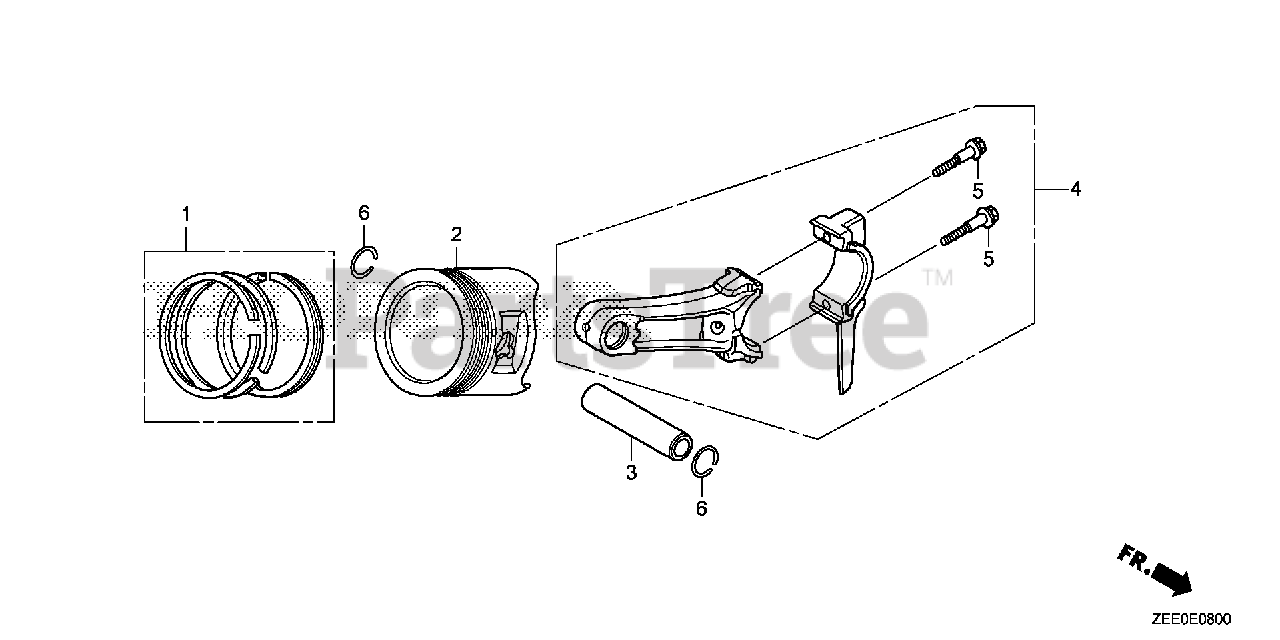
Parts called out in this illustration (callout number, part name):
1	RING SET, PISTON (STD) (TPR)
1	RING SET, PISTON (STD) (RIKEN)
1	RING SET, PISTON (0.25) (TPR)
1	RING SET, PISTON (0.25) (RIKEN)
1	RING SET, PISTON (0.50) (TPR)
1	RING SET, PISTON (0.50) (RIKEN)
1	RING SET, PISTON (0.75) (TPR)
1	RING SET, PISTON (0.75) (RIKEN)
2	PISTON (STD)
2	PISTON (0.25)
2	PISTON (0.50)
2	PISTON (0.75)
3	PIN, PISTON
4	ROD ASSY., CONNECTING (UNDER SIZE)
4	ROD ASSY., CONNECTING (JLH)
4	ROD ASSY., CONNECTING
5	BOLT, CONNECTING ROD (IDENT MARK Z)
6	CLIP, PISTON PIN (18MM)
